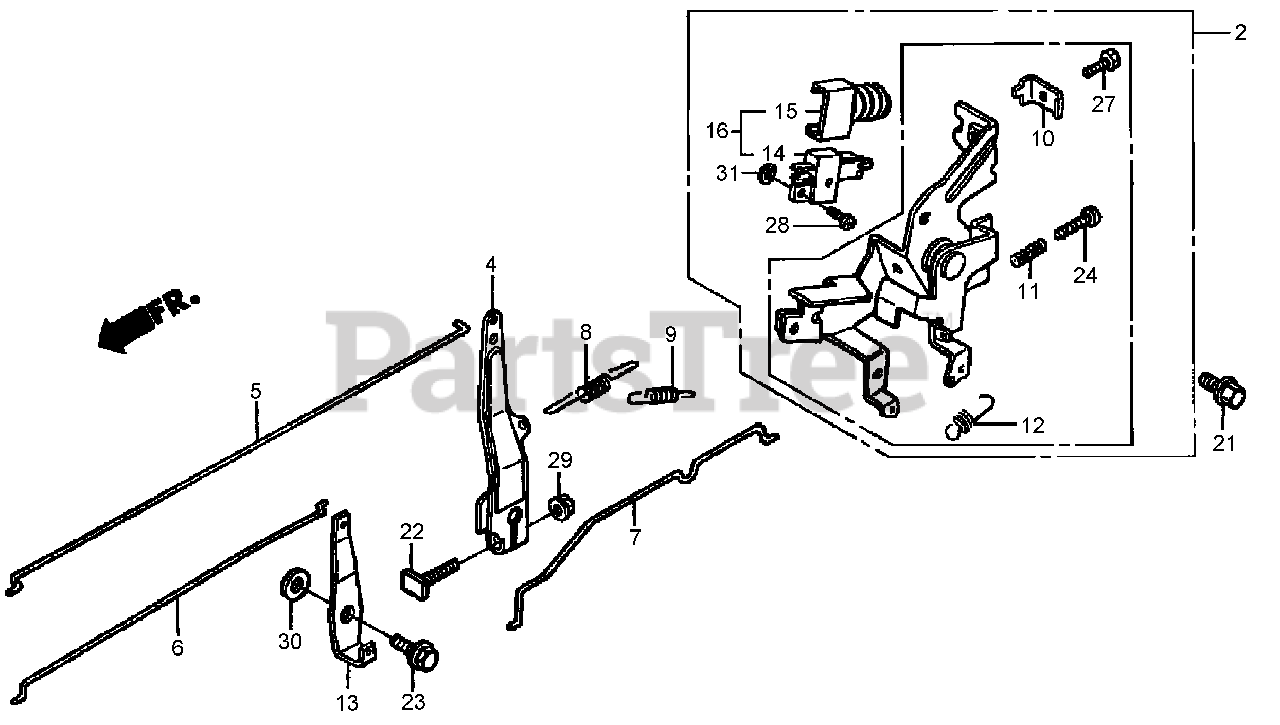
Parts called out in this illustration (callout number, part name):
2	CONTROL ASM
4	ARM-GOVERNOR
5	ROD-GOVERNOR
6	ROD-CHOKE
7	ROD-JOINT
8	SPRING-GOVERNOR
9	SPRING-PRIMARY, GOVERNOR
10	Holder-Cable
11	SPRING-ADJUSTING, CONTROL
12	SPRING-RETURN, CABLE
13	LEVER-JOINT, CHOKE
14	ENGINE SWITCH ASM
15	COVER-SWITCH
16	ENGINE STOP SWITCH ASM
21	BOLT-FLANGE (6X12) (C T200)
22	BOLT-ARM, GOVERNOR
23	BOLT-FLANGE (6MM)
24	Screw-Pan (5X20)
27	BOLT-RECESSED (5X14)
28	SCREW-PAN (4X14)
29	NUT-FLANGE (6 mm)
30	WASHER-PLAIN (6MM)
31	WASHER-SPRING (4MM)
